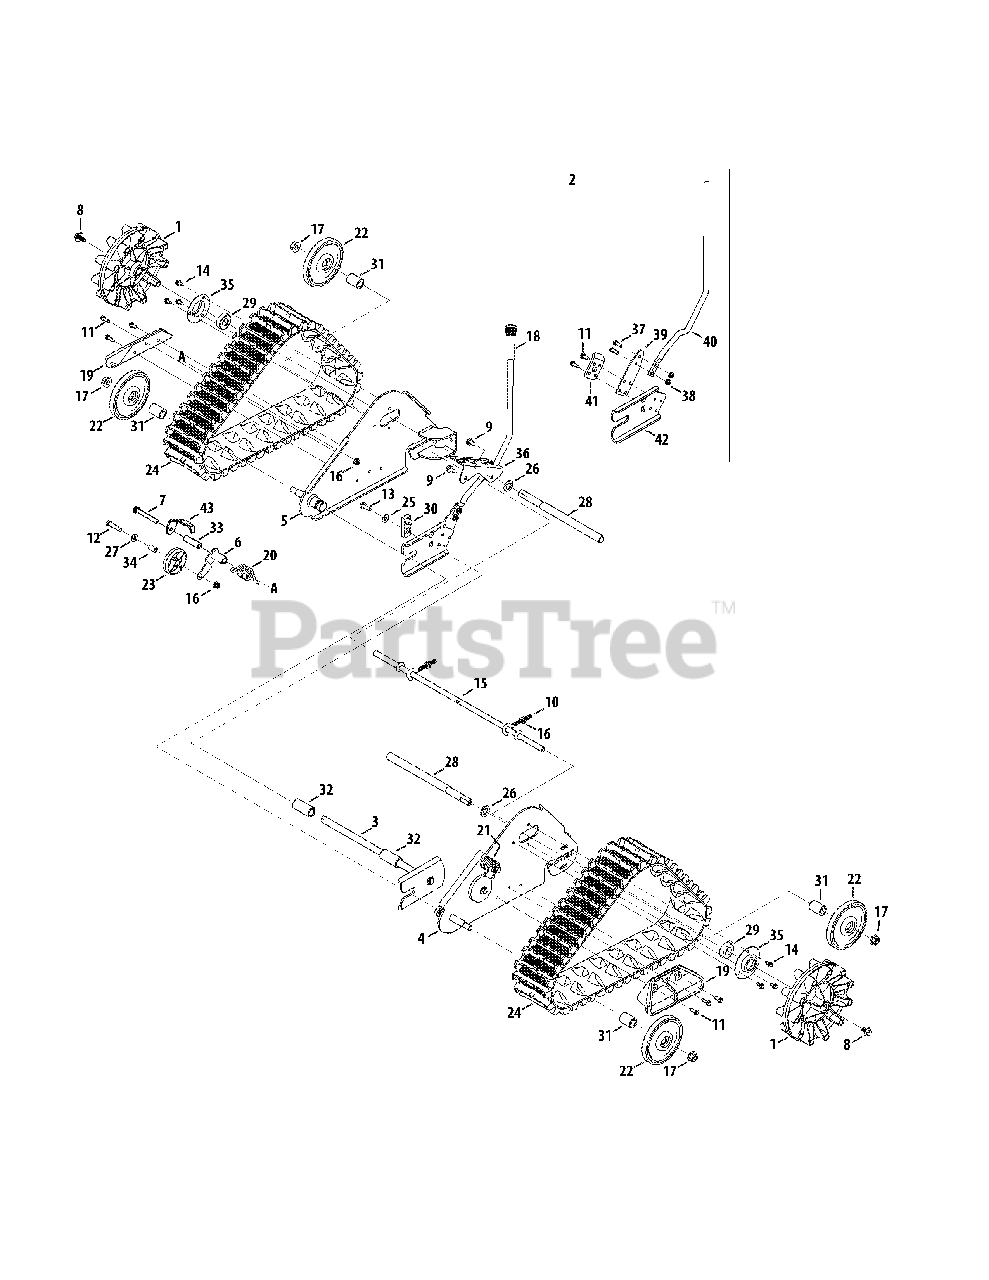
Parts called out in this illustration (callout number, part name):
1	Track Drive Wheel
2	Height Adjustment Lever Assembly
3	Pivot Bracket Assembly
4	Track Mount Plate Assembly, LH
5	Track Mount Plate Assembly, RH
6	Pivot Tension Bracket Assembly
7	Hex Screw, 5/16-18, 2.50, Gr5
8	Screw, 5/16-24 x .750
9	Hex Washer Screw, 5/16-18 x .875
10	Eye Bolt, 5/8 x 2.375, 5/16-18
11	Hex Washer Screw, 1/4-20 x .625
12	Hex Cap Screw, 5/16-18 x 1.50
13	Hex Washer Screw, 5/16-18 x .875
14	Hex Washer Screw, 1/4-20 x .625
15	Rear Wheel Axle
16	Nut, Flange lock, 5/16-18
17	Flange Lock Nut, 1/2-13
18	Grip, .5 ID x 3.45
19	Track Skid
20	Torsion Spring
21	Torsion Spring
22	Wheel, 5.00 OD
23	Track Tension Wheel
24	Track, 61mm x 22 Pitches
25	Washer, Bell, .340 x .872
26	Flat Washer, .672 x 1.125 x .125
27	Flat Washer, .344 x .750 x .120
28	Axle, .75 OD x 11.06 LG
29	Ball Bearing, 17 x 40 x 12
30	Height Adjustment Adapter
31	Spacer, .63 x 1.00 x 1.42
32	Spacer, .632 x 1.00 x 1.42
33	Sleeve, .33 x .50 x 1.73
34	Sleeve, .33 x .50 x .75
35	Cup Bearing
36	Height Adjustment Index Bracket
37	Hex Cap Screw, 1/4-20 x .75
38	Nut, Flangelock, 1/4-20
39	Lever Mounting Bracket
40	Height Adjustment Lever
41	Lever Pivot Bracket
42	Height Adjustment Pivot Bracket
